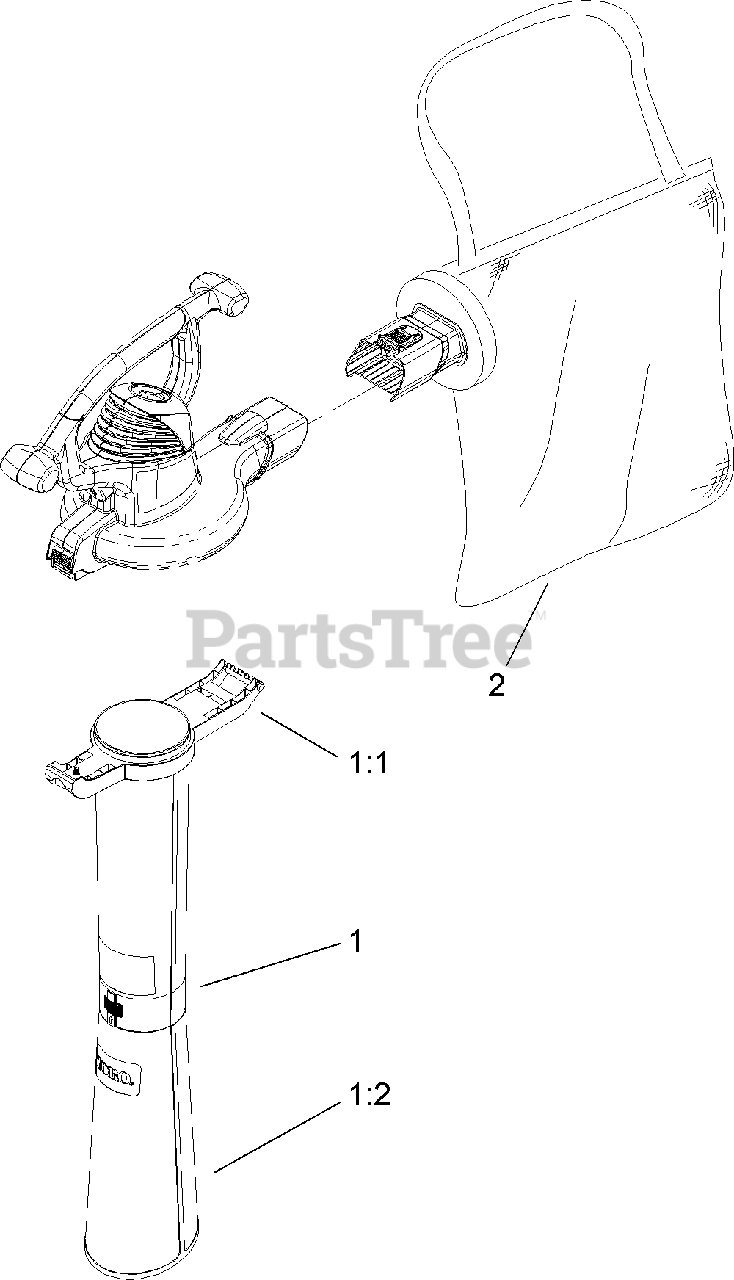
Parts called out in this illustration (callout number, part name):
1	Vac Tube ASM (Not serviced separately)
1:1	TUBE-VAC, UPPER
1:2	TUBE-VAC, LOWER
2	BAG ASM
